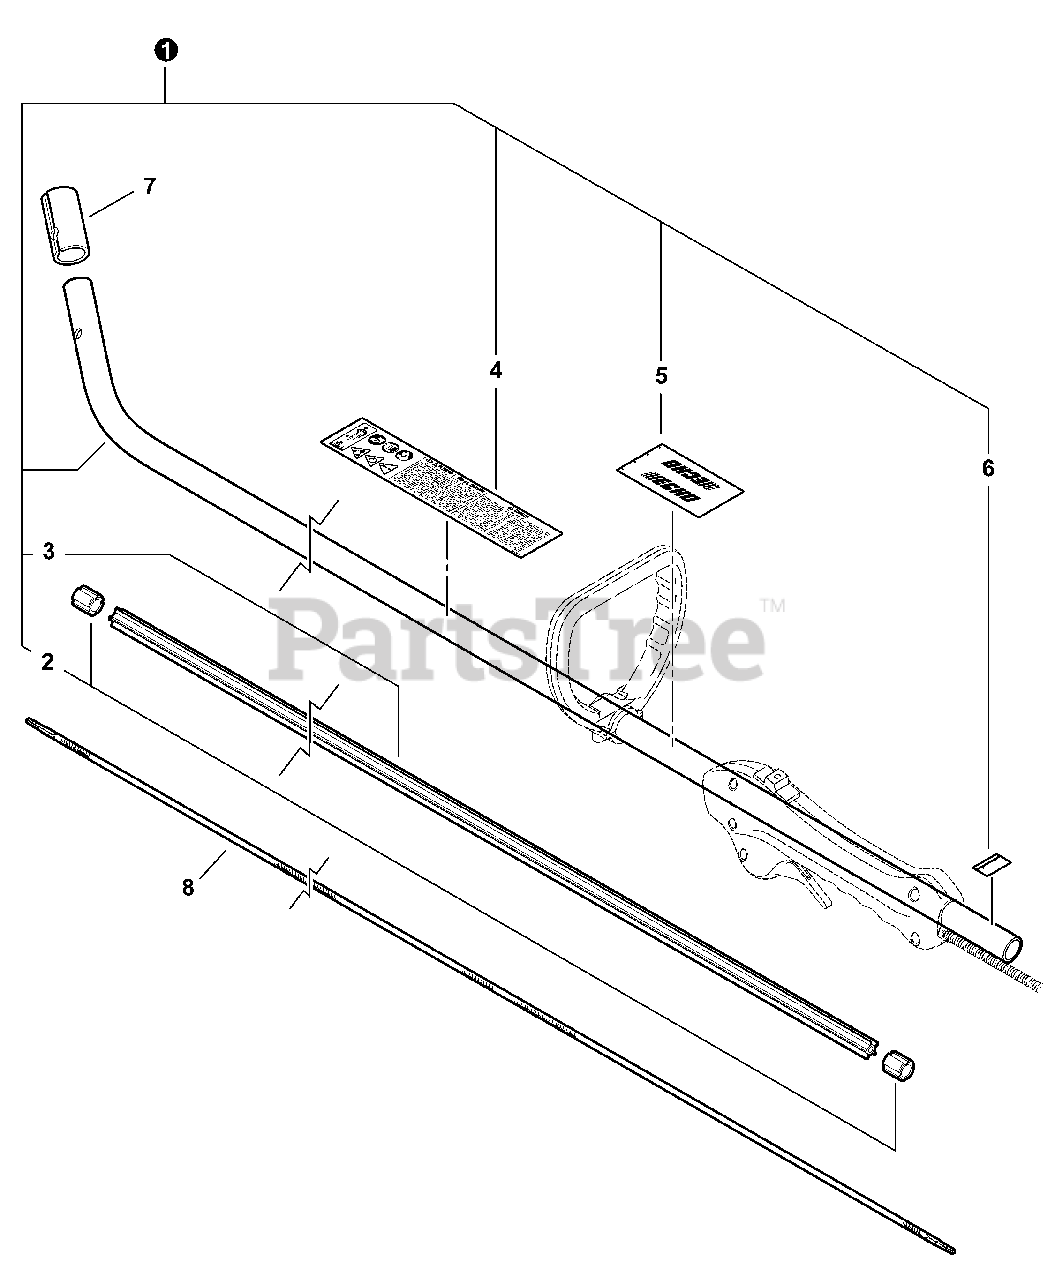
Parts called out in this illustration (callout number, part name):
1	MAIN PIPE ASY
3	LINER - FLEXIBLE
4	LABEL - CAUTION
5	LABEL - HANDLE LOCATION
6	LABEL - ALIGNMENT
8	DRIVESHAFT - FLEXIBLE
